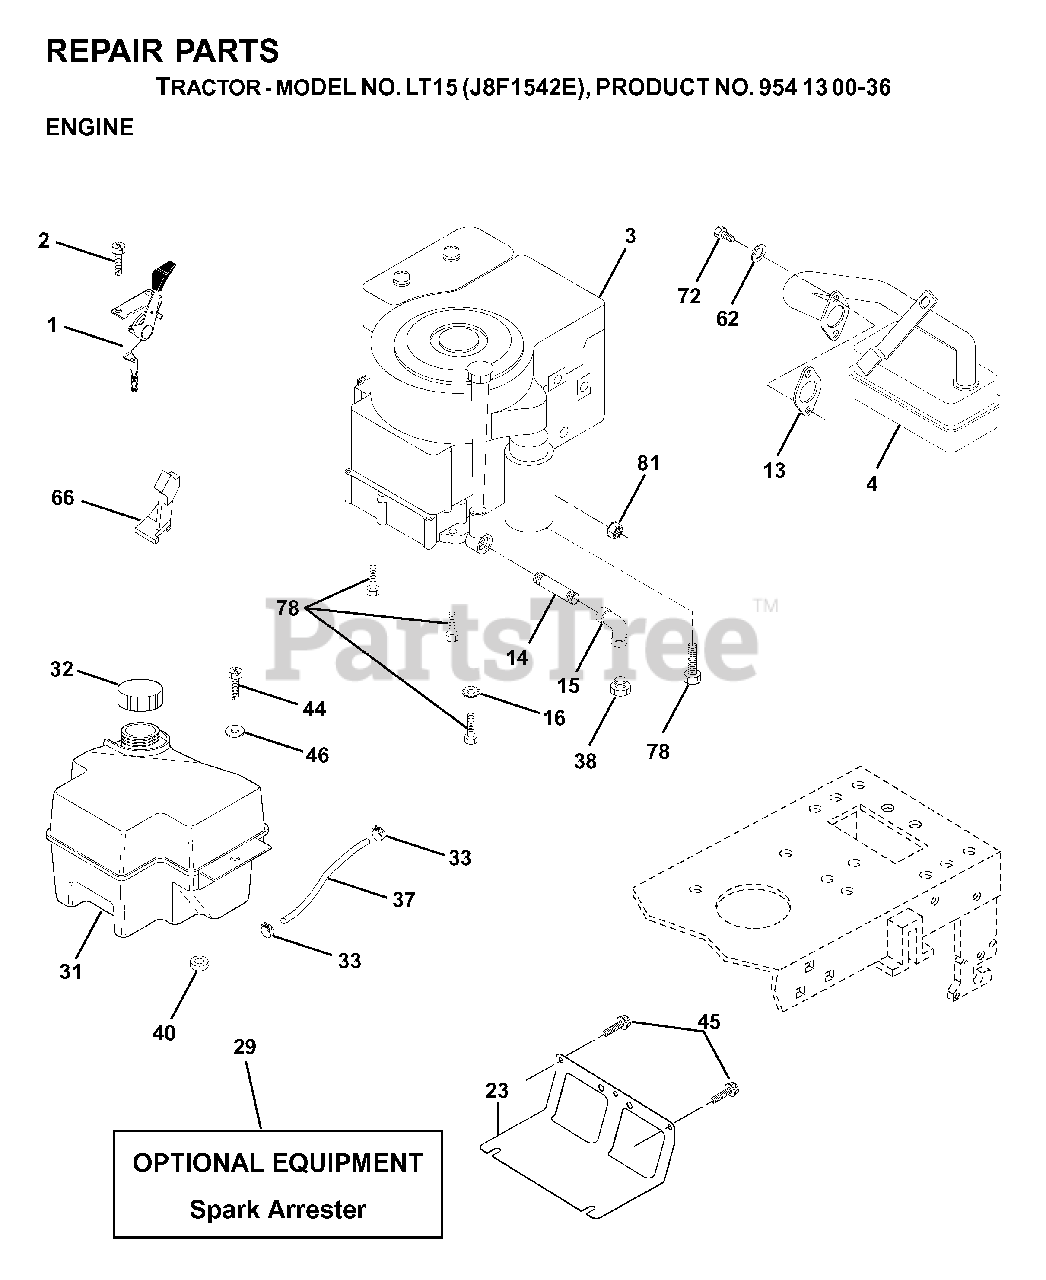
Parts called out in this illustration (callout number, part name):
1	CONTROL
2	SCREW LT
13	REPL BY 532 27 22-93
15	ELBOW
16	LOCKWASHER
23	SHEILD.BROWNING.DBR.GUARD
29	ARRESTER SPARK (OPTIONAL)
31	FUEL TANK
32	FUEL CAP
33	HOSE CLAMP
37	LINE.FUEL.20
40	GROMMET T
44	SCREW HEX CRT
45	SCREW 3/8-16X3/4
62	LOCKWASHER
66	STOP THROTTLE
72	SCREW
78	SCREW.3/8-16
81	NUT FLANGE 1/4-20 STARTER NUT
